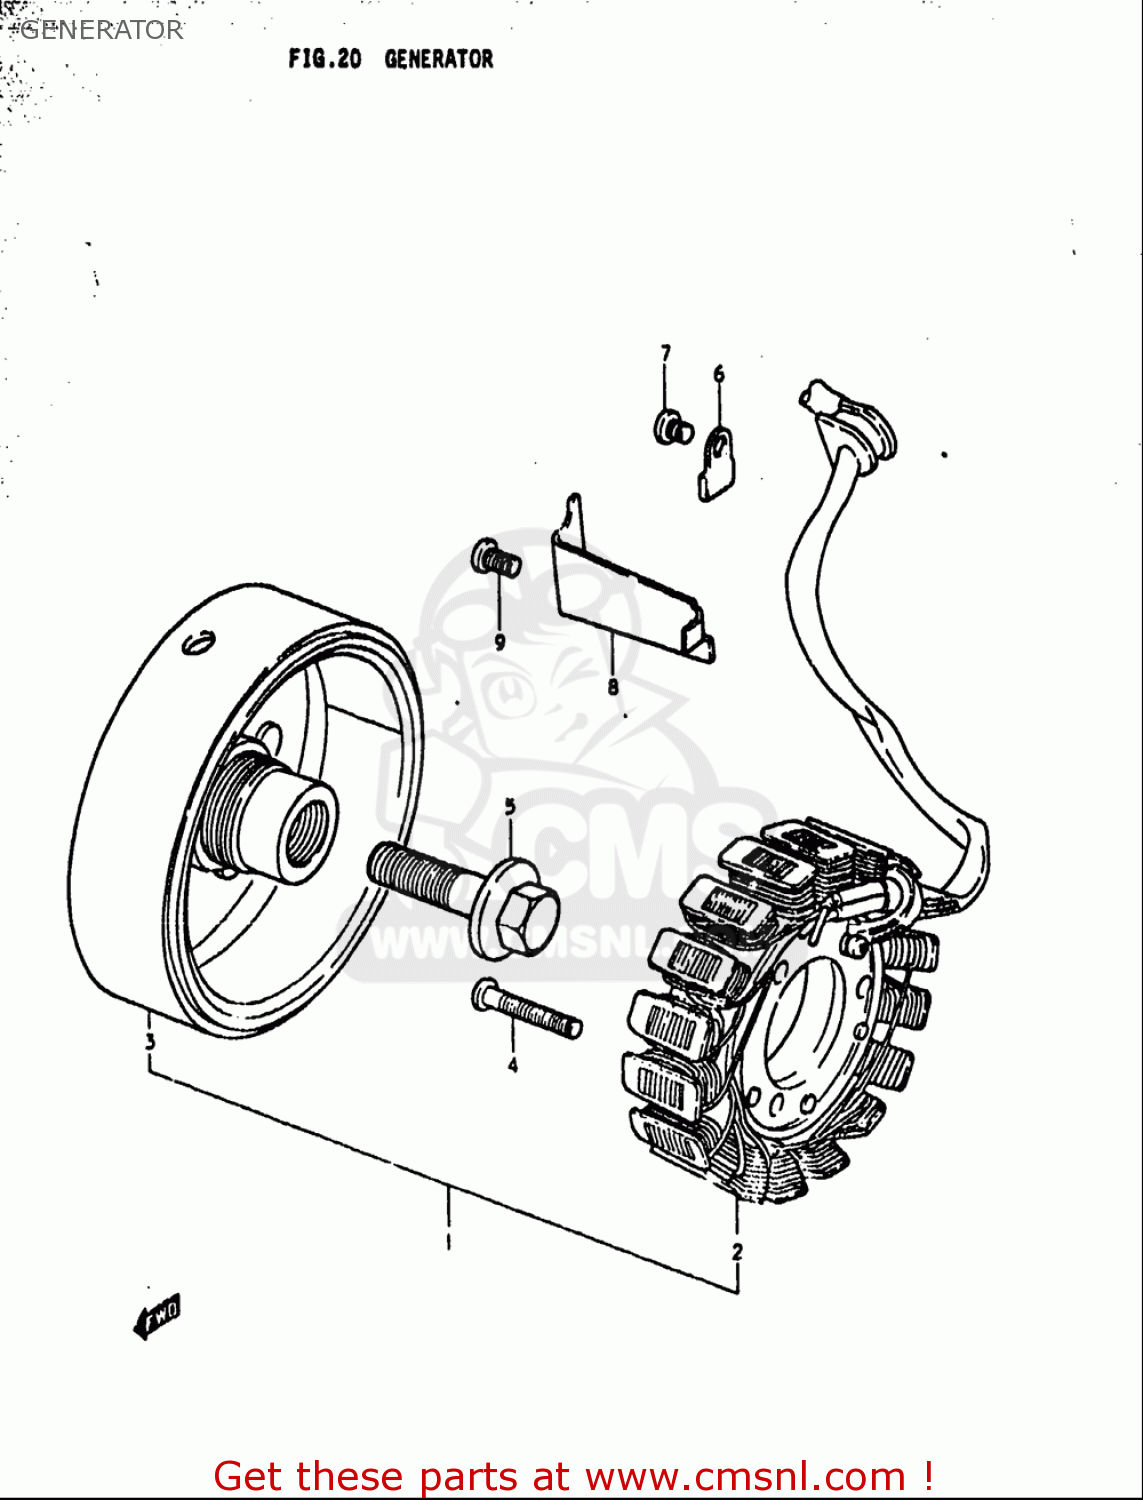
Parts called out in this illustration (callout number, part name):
1	STARTER ASSY
2	STARTER ASSY
4	SCREW
5	BOLT 12X45
6	CLAMP,GENERATOR LEAD WIRE
7	SCREW(5X6)
8	CLAMP,GENERATOR LEAD WIRE
9	SCREW
